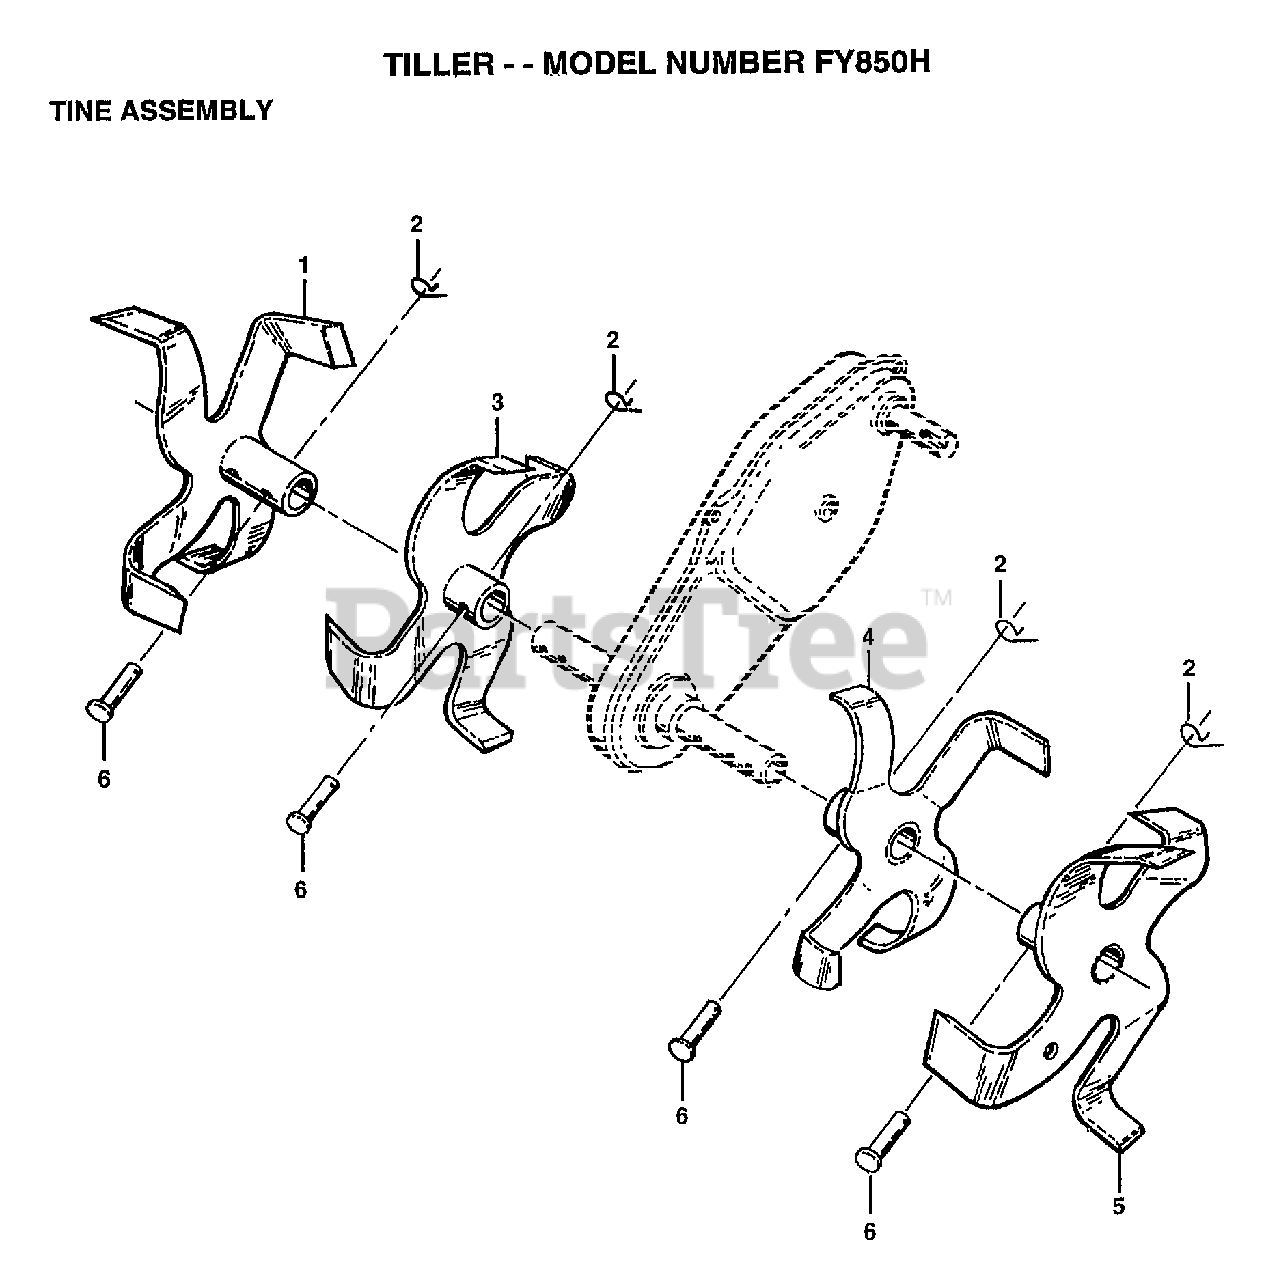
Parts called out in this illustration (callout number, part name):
1	"TINE ASM OUTER,RH"
2	RETAINER SPRING
3	"TINE ASM INNER,RH"
4	TINE ASM INNER LH
5	"TINE ASM OUTER,LH"
6	RIVET.PAN HD.1.75
